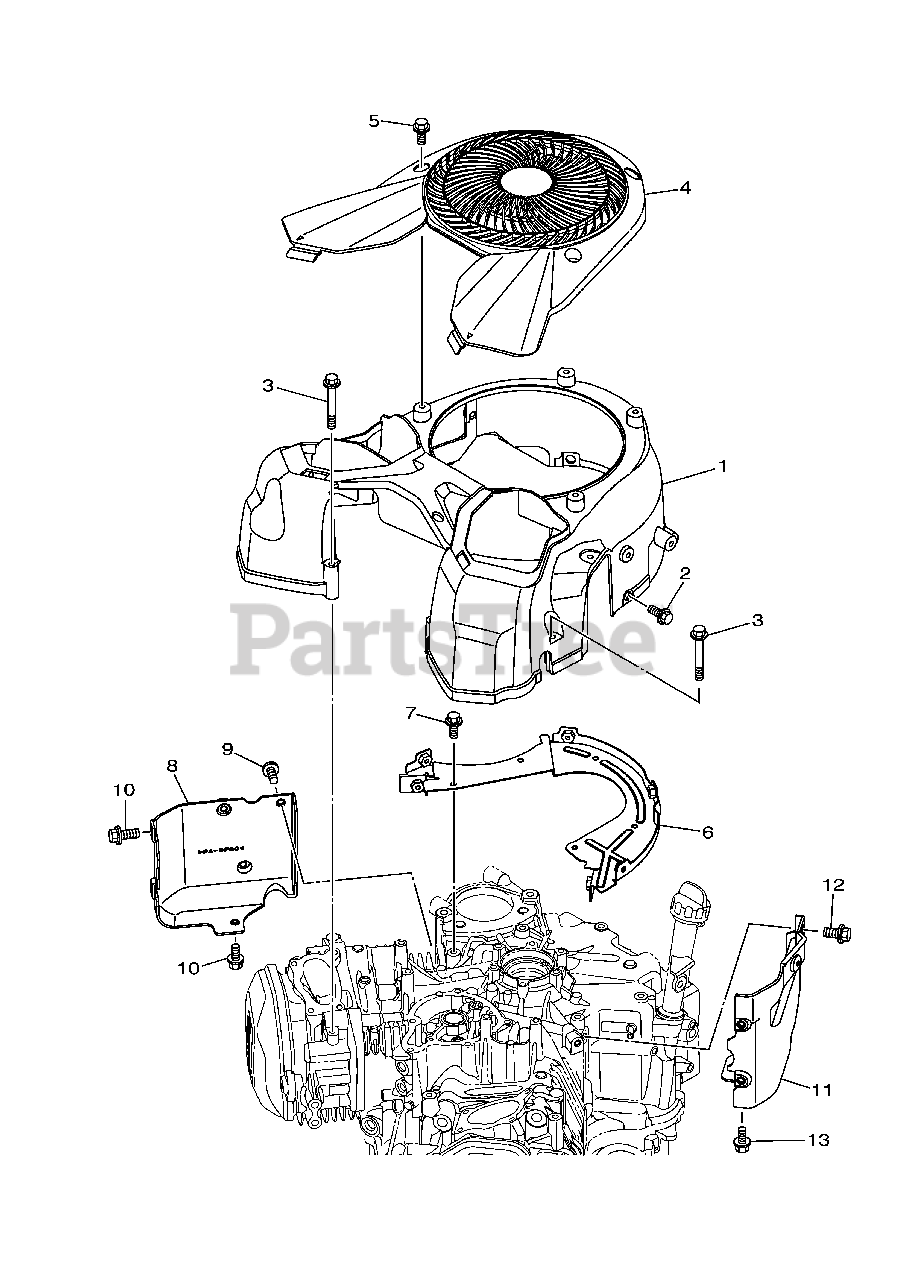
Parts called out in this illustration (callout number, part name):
1	CASE, FAN
3	BOLT, FLANGE
4	COVER, FAN CASE
6	SCROLL, AIR SHROUD
7	BOLT, FLANGE
8	AIR SHROUD, CYLINDER 1
9	BOLT, FLANGE
10	BOLT, FLANGE
11	AIR SHROUD, CYLINDER 3
12	BOLT, FLANGE
13	BOLT, FLANGE
